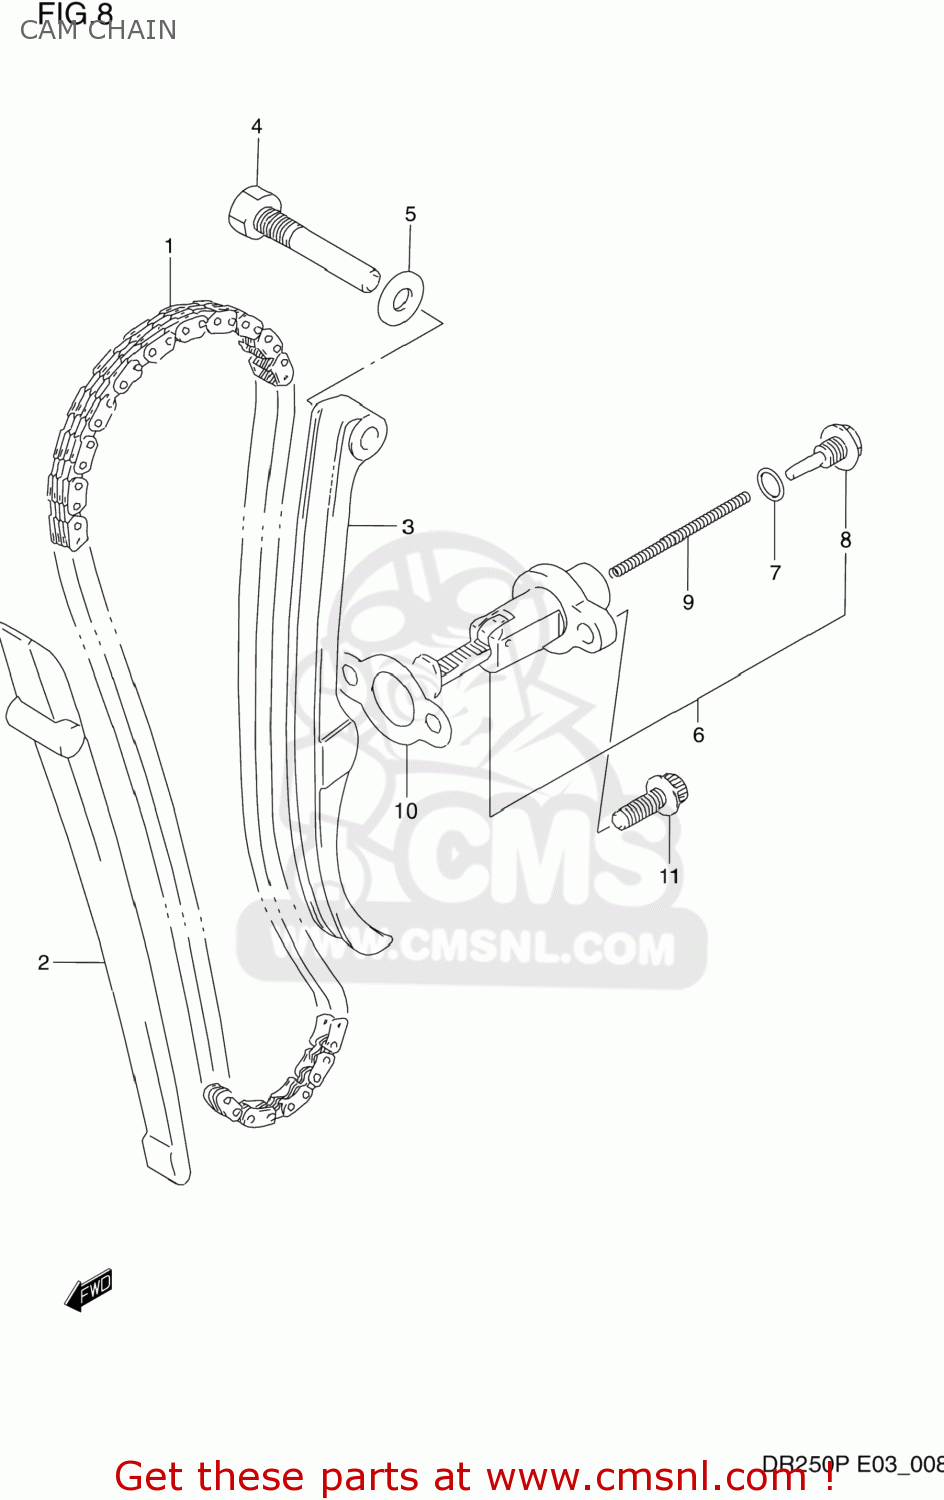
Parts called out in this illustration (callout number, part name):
1	CHAIN,CAMSHAFT DRIVE
2	GUIDE,CAM CHAIN
3	TENSIONER,CAM CHAIN
4	BOLT,CAM CHAIN TENSIONER
5	GASKET 8.2X14X1 (NAS)
6	ADJUSTER ASSEMBLY,TENSIONER
7	O RING
8	PLUG,ADJUSTER
9	SPRING
10	GASKET,TENSIONER ADJUSTER(NA) (NAS)
11	PLUG ,6X20
